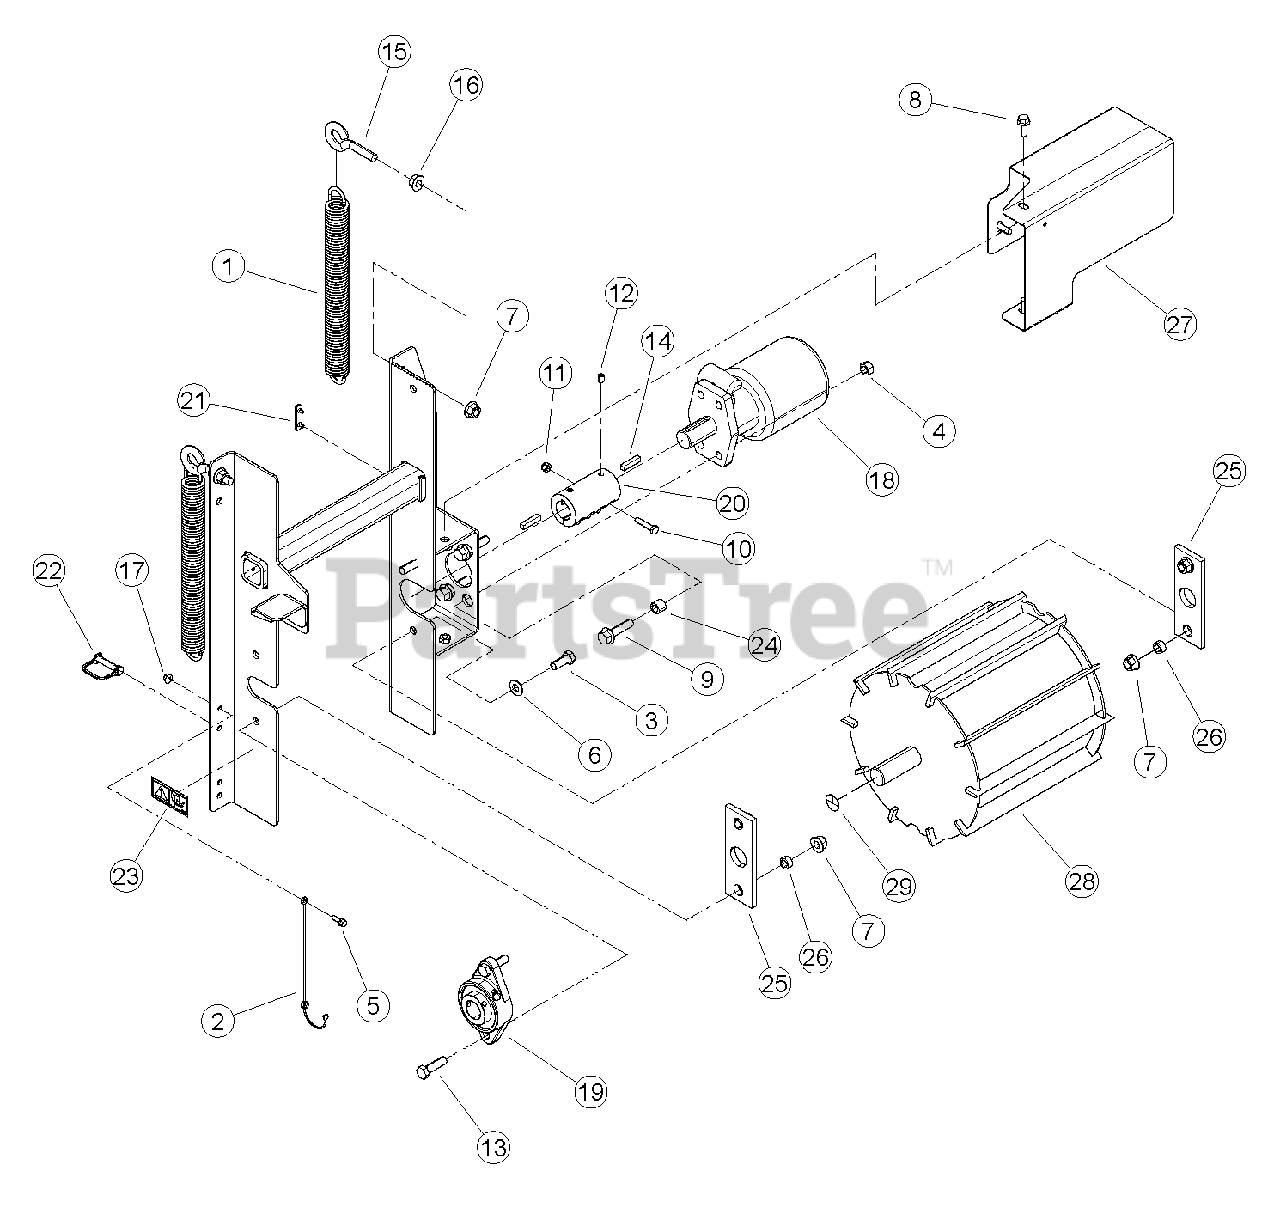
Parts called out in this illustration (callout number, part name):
1	SPRING, EXTENSION
2	LANYARD, NYLON
3	BOLT, 1/2 X 1-1/4" GR5 HHCS NC ZP
4	NUT, 1/2" CENTERLOCK GRB ZP
5	BOLT, 1/4-20 X 3/4 HWH GR5 CZP
6	WASHER, 1/2" SAE FLAT ZP
7	NUT, 1/2-13 NYLOCK FLANGE
8	BOLT, 3/8 X 1 FLANGE NC
9	BOLT, 1/2-13 X 2 HWH GR5 CZP
10	BOLT, 5/16 X 1-1/2 GR5 HEX CPS ZP
11	NUT, 5/16" NE NYLOCK ZP
12	SET SCREW, 3/8 X 1/2 CUP PT SKT
13	BOLT, 1/2 X 1 3/4 GR5 HCPS NC ZP
14	KEY, 5/16 X 1-1/2 SQUARE
15	EYEBOLT, 1/2 X 2" ZP
16	NUT, 1/2 SPIRAL LOCK NC ZP
17	NUT, 1/4-20 NYLOCK-FLANGE
18	MOTOR, 45 CU IN HYDRAULIC
19	BEARING, 1-1/4" DIA 2 BOLT FLANGE
20	COUPLER, 1-1/4 SHAFT
21	WEAR PAD, STD. SPRING HD FRONT
22	PIN, SNAP 3/8 X 1-1/2 USABLE LGH
23	DECAL, CRUSHING ISO
24	SPACER, 0.75 X 0.620
25	BEARING, SLIDE
26	SPACER, .75 OD X .5 ID X .37
27	WELDMENT, MOTOR COVER
28	ASSEMBLY, 6" FEED ROLLER SERVICE
29	DECAL, ROTATING SHAFT
